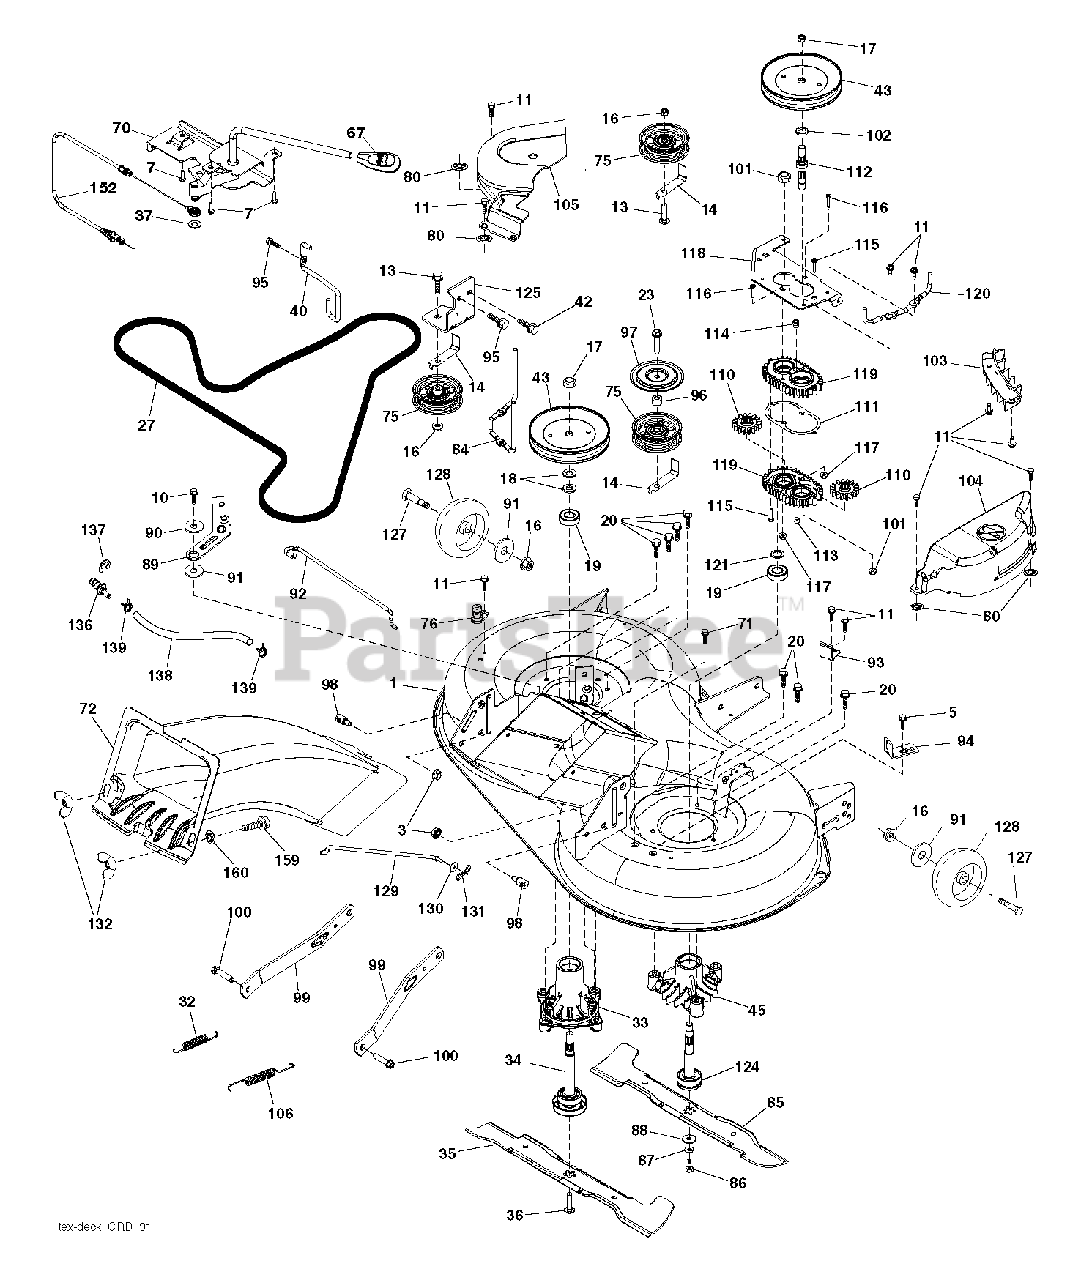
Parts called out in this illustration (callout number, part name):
3	NUT LOCK HEX FLANGE 5/16-18
5	BOLT.5/16HEX.WHS.HD
7	SCREW.#10 X 0.750.BOS THREAD
10	SCREW 3/8-16X1
11	SCREW.1/4-20X5/8
13	BOLT.3/8-16X1.50
14	KEEPER, BELT IDLER
16	NUT LOCK FLG 3/8-16 UNC
17	NUT.FLANGE.LOCK.TOP
18	WASHER.SPACER.MANDREL
20	SCREW, WASHER HEAD
23	SCREW LT
32	SPRING RETURN
33	HOUSING MANDREL
34	SHAFT.ASM.MDRL.N/GREASE.38
35	BLADE.3N1.LH.CRD.97
36	BOLT.WASHER.ASM.7/16-2
40	KEEPER BELT ENGINE LH
42	SCREW
43	PULLEY.MANDREL.5.438.PD
45	HOUSING.MANDREL
67	HANDLE.CLUTCH.CABLE.LT
70	CLUTCH.ASM.MANUAL.LT.PRED
71	SCREW 3/8-16X1/2
75	FLAT IDLER PULLEY
76	PORT.WASHOUT
80	PALNUT 1/4
84	KEEPER.BELT.MANDREL.PULLEY
85	BLADE.3N1.RH.CRD.97
87	LOCKWASHER
88	WASHER.BLADE
90	SPACER.RETAINER
94	BRKT.CLUTCH.CABLE
95	SCREW, 3/8-16X3/4
98	STUD.FASTNER.W/ANTI-ROTATE
99	ARM.SUSPENSION.MOWER.R
100	BOLT.SHOULDER
102	SPACER BEARING
106	SPRING.BRAKE.RETURN.38"
117	NUT T
127	BOLT.SHOULDER.3/8-16X3-5/8
128	WHEEL. GUAGE RALLY
129	ROD.ANTI.SWAY.48/54"K4
130	WASHER
131	PIN.COTTER.5/16.BOW TI
132	KNOB.HANDLE.3/8.TRI-POINT.BLAC
137	RING CLIP
159	BOLT
